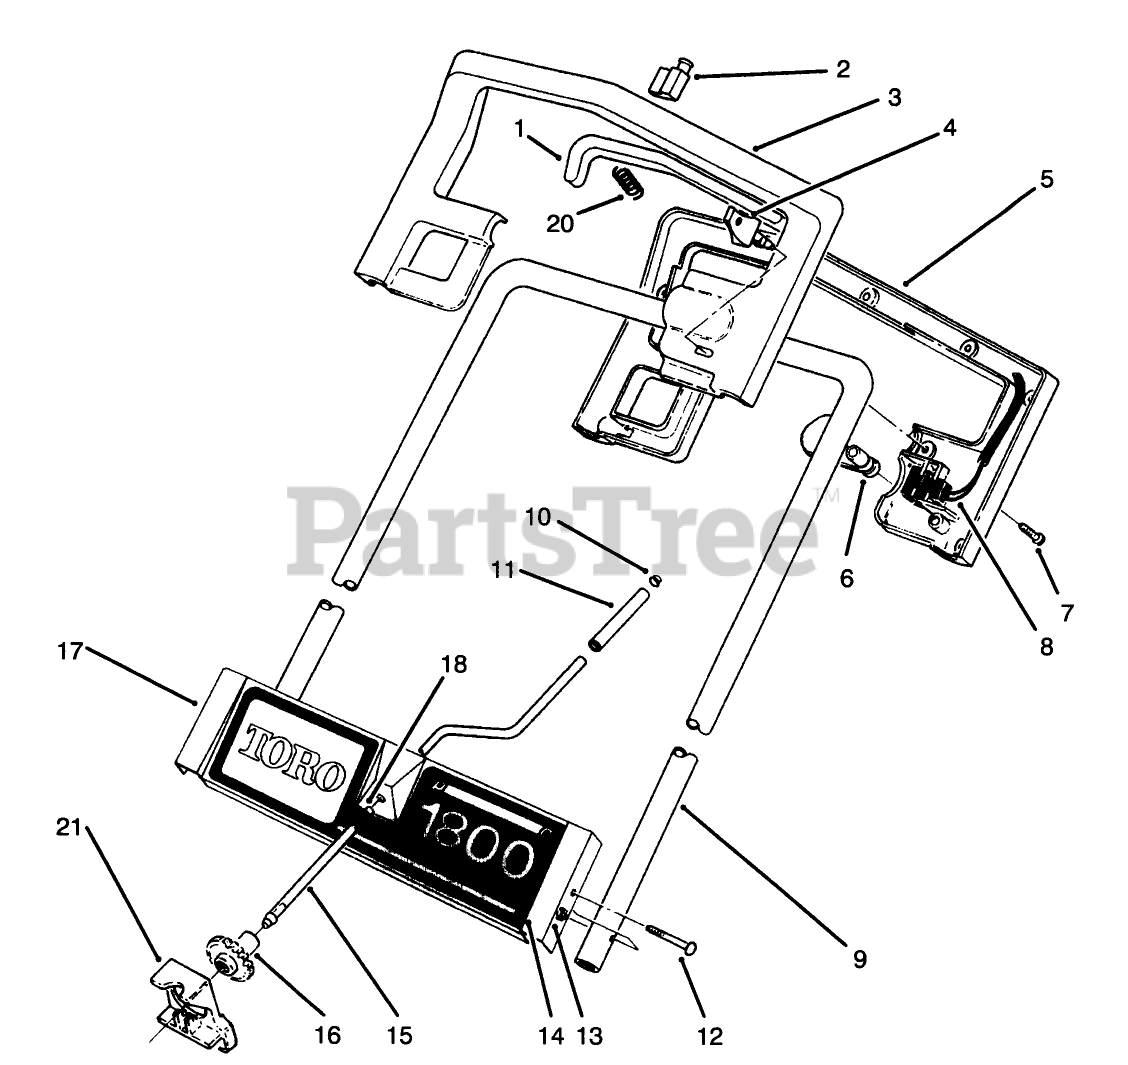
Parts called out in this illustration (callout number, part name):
1	Bar-Switch
2	SWITCH
3	Handle-Control, Upper
5	Handle-Control, Lower
6	Tab-Lock
7	Screw
8	Cord-Supply
9	Tube-Handle, Upper
10	PUSHNUT-CAP, WASHER
11	Sleeve-Crank, Chute
12	Screw-HH
13	NUT-LOCK, NI
14	DECAL - ESCUTCHEON
15	Rod-Crank, Chute
16	Gear-Crank, Chute
17	Plate-Escutcheon
18	Bushing-Nyliner
20	Spring
21	Brake-Gear
